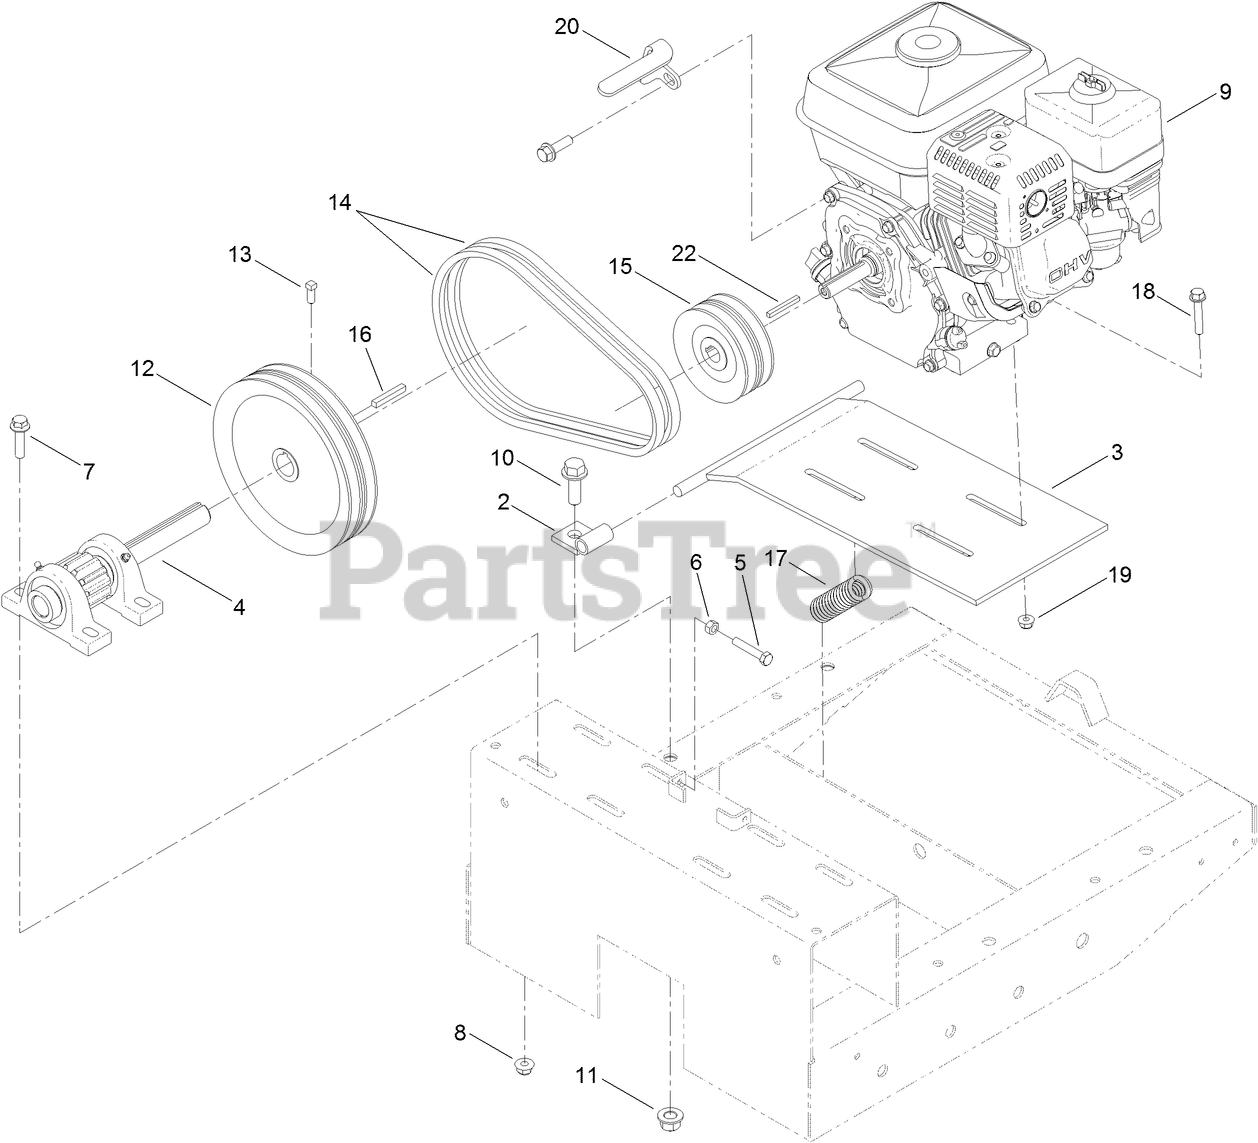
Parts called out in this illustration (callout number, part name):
2	MOUNT-MOTOR
3	BASE-MOTOR
4	PINION ASM
5	SCREW-HH
6	NUT-HEX
7	SCREW-HHF
8	NUT-HF, NI
9	ENGINE-HONDA, GX240
10	SCREW-HHF
11	NUT-LOCK
12	SHEAVE
13	SCREW-SET, SQH
14	BELT-V
15	SHEAVE
16	KEY-SQUARE
17	SPRING
18	SCREW-HHF
19	NUT-HF, NI
20	GUIDE-BELT
22	KEY-SQUARE
